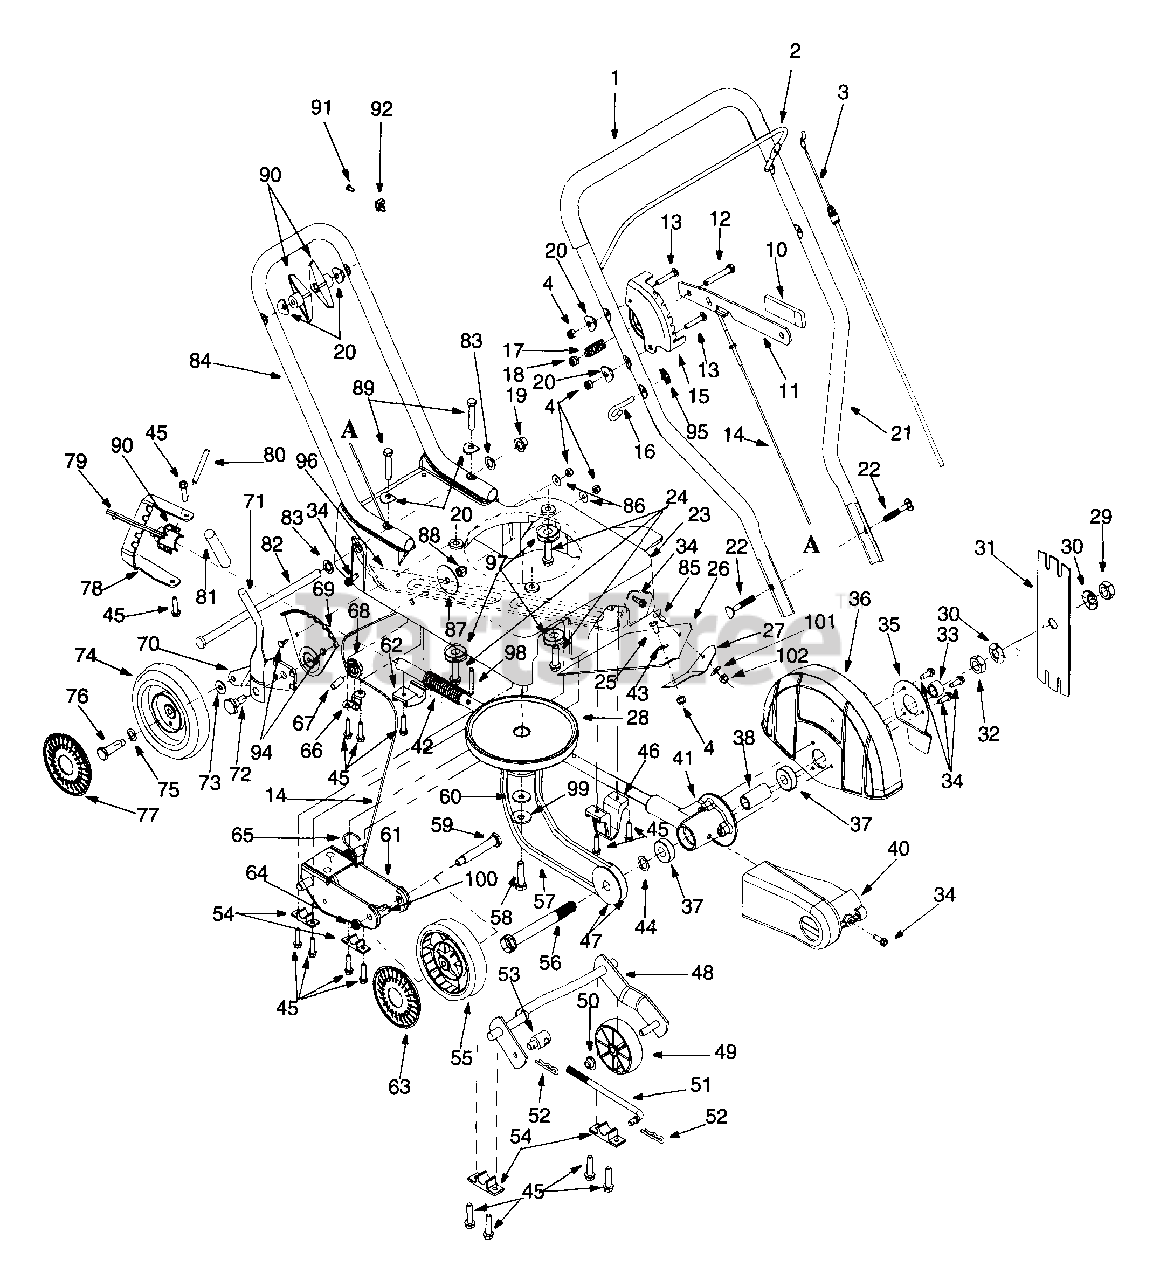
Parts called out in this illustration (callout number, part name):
3	Control Cable 34" B&S
4	Hex Lock Nut 1/4-20
10	Depth Lever Grip
12	Hex Screw 5/16-18 x 2.0 Lg.
13	Thrust Screw 1/4-20 x 1.5
15	Depth Bracket
16	Eye Bolt 1/4-20
17	Compression Spring .550 O.D. x 1.3
18	Hex Lock Nut 5/16-18
20	Washer .320 ID x .93 O.D.
23	Edger Base Ass'y
24	Tapp Screw w/Hex Lock Wash 3/8-16
25	Hex Screw 1/4-20 x .50 Lg.
26	Discharge Shield Deflector
27	Deflector Keeper
28	Engine Pulley
29	Hex Jam Nut 5/8-18
30	Bell Washer .63 I.D. x 1.25 O.D. x .18
32	Hex Jam Nut 5/8-18
33	Spacer .628 x .875 x .545 Lg.
34	Hx Scr. w/Wash.: TT: 1/4-20 x .750 Lg.
37	Ball Bearing .62 I.D. x 1.38 O.D. x .4
38	Spacer .628 x .875 x 1.818 Lg.
41	Spindle w/Insert
42	Compression Spring
43	Flat Washer .283 I.D. x .75 O.D. x .030
44	Flat Washer .635 I.D. x .93 O.D. x .06
45	Hex Screw w/Wash 1/4
46	Front Rod Handler
47	Pulley
52	Cotter Pin .072 x 1.12
53	Ferrule 5/16-24 x .312
54	Black Bushing .515 Dia. x .62
56	Hex Bolt 5/8-18 x 5.25 Lg.
57	V-Belt
58	Hex Screw: 3/8-24 x 1.50 Lg.
59	Shoulder Screw .500 x 2.62: 3/8-16
60	Flat Washer .38 OD x 1.38 OD
61	Front Wheel Brkt Ass'y.
62	Rear Rod Handler
63	Hubcap: Spoke w/Hole Grey
64	Jam Lock Nut 3/8-16
65	Torsion Spring
68	Cable Roller Pulley
69	Index Plate
71	Spring Lever
72	Shoulder Bolt .500 x .434 Lg.
73	Bell Wash. .401 ID. x .870 OD. x .063
75	Wave Washer .510 I.D. x .750 O.D.
76	Shoulder Bolt .498 x 1.445: 3/8-16
77	Hubcap: Radial Spoke Grey
78	Tilt Bracket
79	Adj. Lever Ass'y
80	Pin 1/4 x 2.0" Lg.
83	Flat Wash. .531 I.D. x .875 O.D. x .06
86	Flat Wash. .285 ID x 1.25 OD x .06
87	Flat Wash. .406 ID x 1.92 OD x .06
88	Hex Lock Nut 3/8-16
89	Hex Screw 5/16-18 x 1.75 Lg.
90	Torsion Spring
90	Wing Knob Nut 5/16-18
91	Hex Scr. w/Wash.: T: #10-32 x .625 Lg.
92	Clamp B&S Throttle
94	Screw Std. 1/4-20 x .75 Lg.
99	Bell Washer .396 ID x 1.14 OD
100	Spacer .520 ID x .860 Lg.
101	Lock Washer 1/4
102	Hex Nut 1/4-20
777D00299	WOP Hub Cap w/Icon
777I20122	Start Instructions / Model Plate
777S30022	Belt Guard Cover
777S30244	Blade Guard Danger
